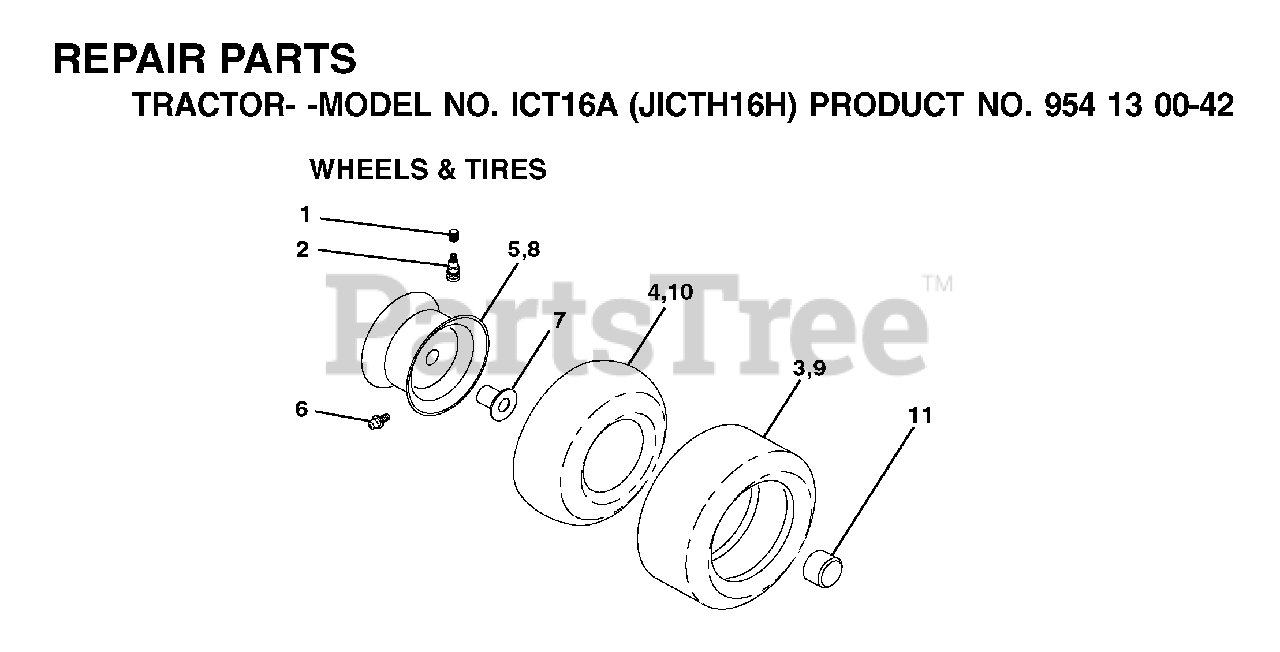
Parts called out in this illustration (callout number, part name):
1	VALVE CAP
2	VALVE STEM LT
3	TIRE HEAVY DUTY
4	TUBE.5.3/4.5/6
5	RIM ASM 6" FRONT SILVER
6	FITTING LT
7	BEARING T
8	RIM ASM 8" REAR SILVER
9	TIRE 20X8-8 TURF SAVER
10	TUBE
11	CAP, AXLE BLK
